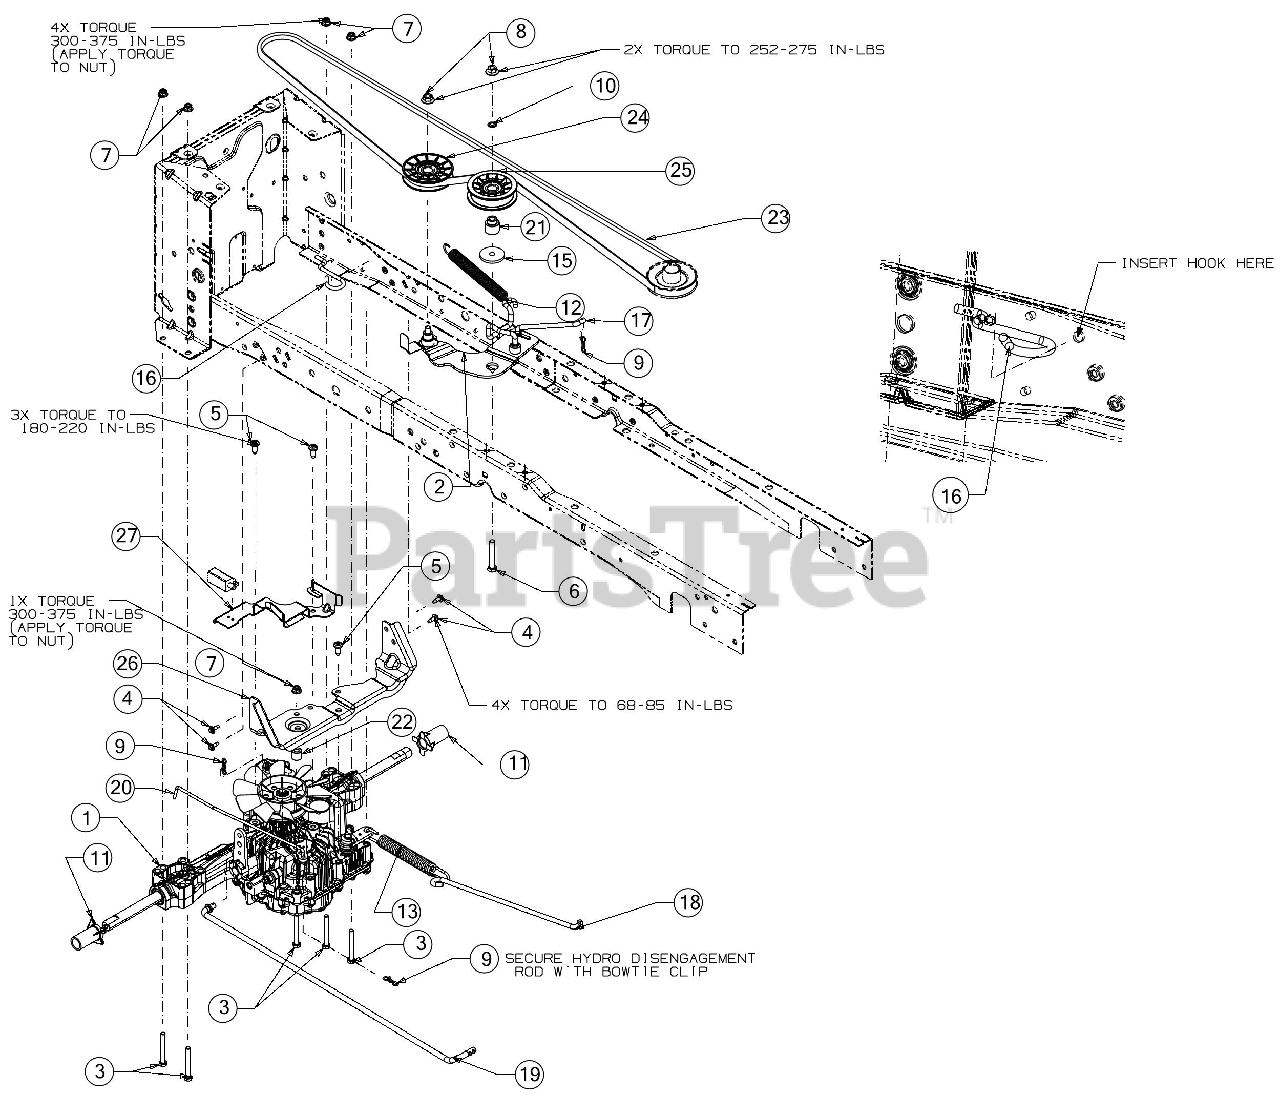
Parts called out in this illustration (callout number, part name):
1	TRANSMISSION ASSEMBLY
2	IDLER BRACKET ASSEMBLY
3	SCREW 5/16-18 X 2.5 GR 5
4	SCREW M6-1 X .625
5	SCREW 5/16-18 X .750
6	SCREW 3/8-16 X 2.25 GR5
7	FLANGE LOCK NUT 5/16-18
8	FLANGE LOCK NUT
9	BOW TIE COTTER PIN 1/4-5/16
10	PUSH NUT
11	AXLE SLEEVE .765 ID X 2.11 LG
12	EXTENSION SPRING .790 DIA X 8.41
13	EXTENSION SPRING
15	SHOULDER SPACER
16	DECK SPRING HOOK
17	IDLER BRACKET LINK ROD
18	BRAKE ROD
19	HYDRO CONTROL ROD
20	HYDRO DISENGAGEMENT ROD
21	SHOULDER SPACER
22	SPACER .34 X .75 X .63 LG
23	V-BELT A SEC X 91.10
24	V-IDLER PULLEY 3.56 OD
25	FLAT IDLER PULLEY 3.00 OD
26	TRANSMISSON MOUNTING BRACKET
